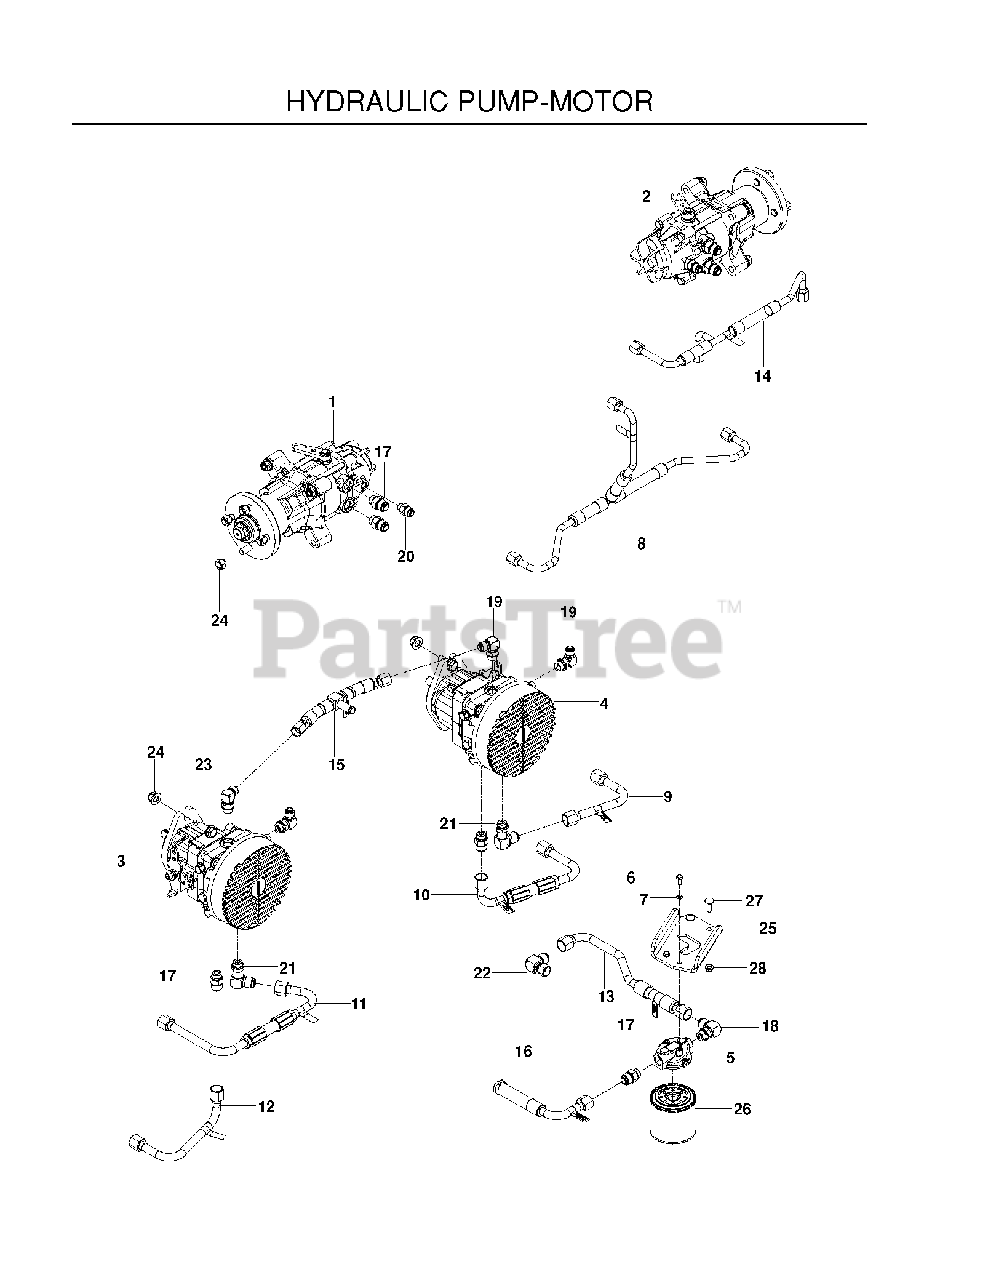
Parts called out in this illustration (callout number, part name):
1	HG_MOTOR, PRM, RT
2	HG_MOTOR, PRM, LT
3	HG_PUMP, 21CC, RT
4	HG_PUMP, 21CC, LT
5	FILTER HEAD
6	HCS 1/4C X 5/8
7	LOCKWASHER 1/4"
8	LINE, HYD, CASE-RM
9	LINE, HYD, LT-AA
10	LINE, HYD, LT-BB
11	LINE, HYD, RT-AB
12	LINE, HYD, RT-BA
13	LINE, HYD, SUCTION
14	LINE, HYD, PUMP
15	LINE, HYD, CHARGE
16	LINE, HYD, CHARGE
17	FITTING, 10-8 STRAIGHT
19	ELBOW, 90 DEGREE
20	FITTING, HYDRO
21	FITTING, 10-8 90 DEG
22	FITTING, HYD, 6500-10-8
23	HCS 1/2C X 1 1/4 SERRATED HEAD
24	LUG NUT 1/2F
25	MOUNT, FILTER, BLK
26	FILTER 25 MICRON
27	RHSNB 5/16C X 1
28	5/16-18 NYLOC FLANGE NUT
